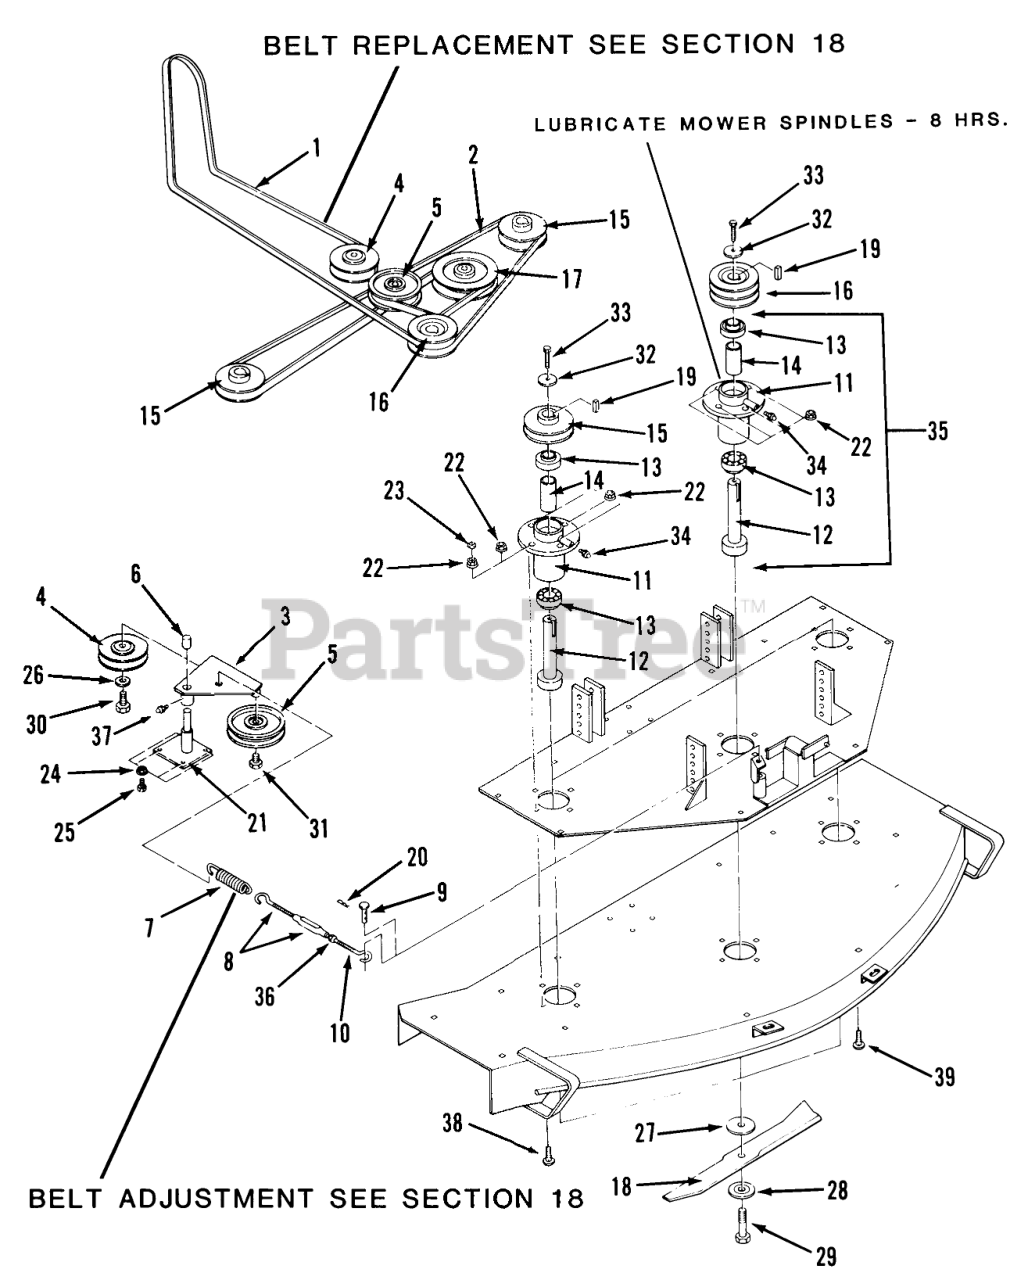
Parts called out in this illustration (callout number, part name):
1	V-BELT
2	Mower Spindle Belt (105.5")
3	Belt Tensioning Swing Arm
4	PULLEY-V IDLER
5	Flat Idler
6	Bronze Bushing
7	SPRING-EXTENSION
8	TURNBUCKLE
9	Idler Spring Pin
10	EYEBOLT B-150-K
11	Mower Hub
12	SHAFT MOWER SPINDLE
13	Mower Bearing
14	Spacer
15	Sheave-1 Groove
16	PULLEY 2-GROOVE
17	Flat Idler
18	Mower Blade 17"
20	Hairpin
21	Belt Tensioning Pivot
22	NUT
23	NUT
24	Hex Nut 1/4-20
25	Bolt
26	Lockwasher
27	WASHER FIBER
28	WASHER CUPPED
29	BOLT HEX 5/8-18X21/2
30	Hex Bolt 5/8-11 x 1
31	Hex Bolt 1/2-13 x 3/4
32	Cupped Washer
33	Bolt 3/8-24 x -1/4
34	ZERK 90DEGREE
35	Spindle Assembly (Includes items 11, 12, 13 & 34)
36	Nut
37	Zerk
38	Bolt
39	Bolt
